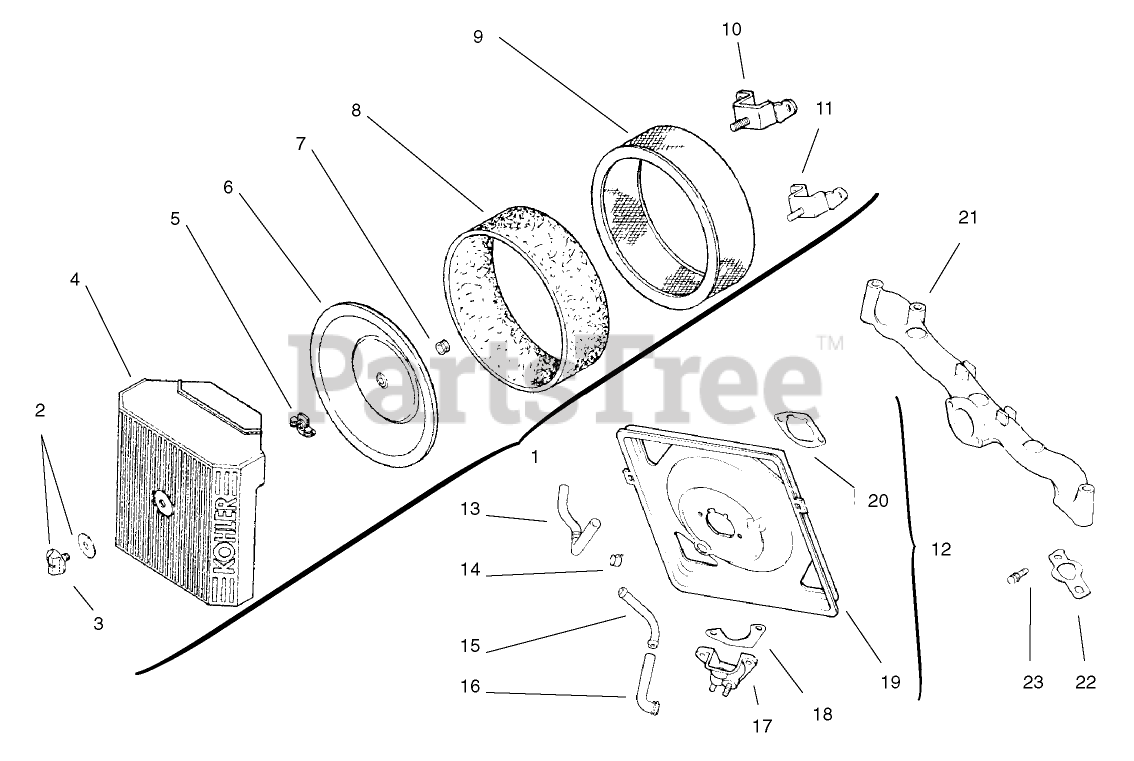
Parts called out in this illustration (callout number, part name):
1	Kit-Air Cleaner Cover
2	Kit-Knob w/Gasket
3	Knob-Cover
4	Cover-Air Cleaner
5	Nut-Wing
6	Cover-Inner Air Cleaner
7	Seal-Air Intake (Only On: 72103)
8	Element-Precleaner
9	Element-Air Cleaner
10	Bracket-Air Cleaner
11	Bracket-Air Cleaner
12	Kit-Air Cleaner Base
13	Hose-Breather
14	Clamp
15	Fitting
16	Hose-Breather
17	Cup-Fuel Spitback
18	Gasket-Fuel Spitback Cup (Only On: 72103, 72083)
19	Base-Air Cleaner
20	Gasket-A/C Base (Only On: 72103, 72083)
21	Manifold-Intake (Only On: 72103)
22	Gasket-Intake Manifold
23	Screw
